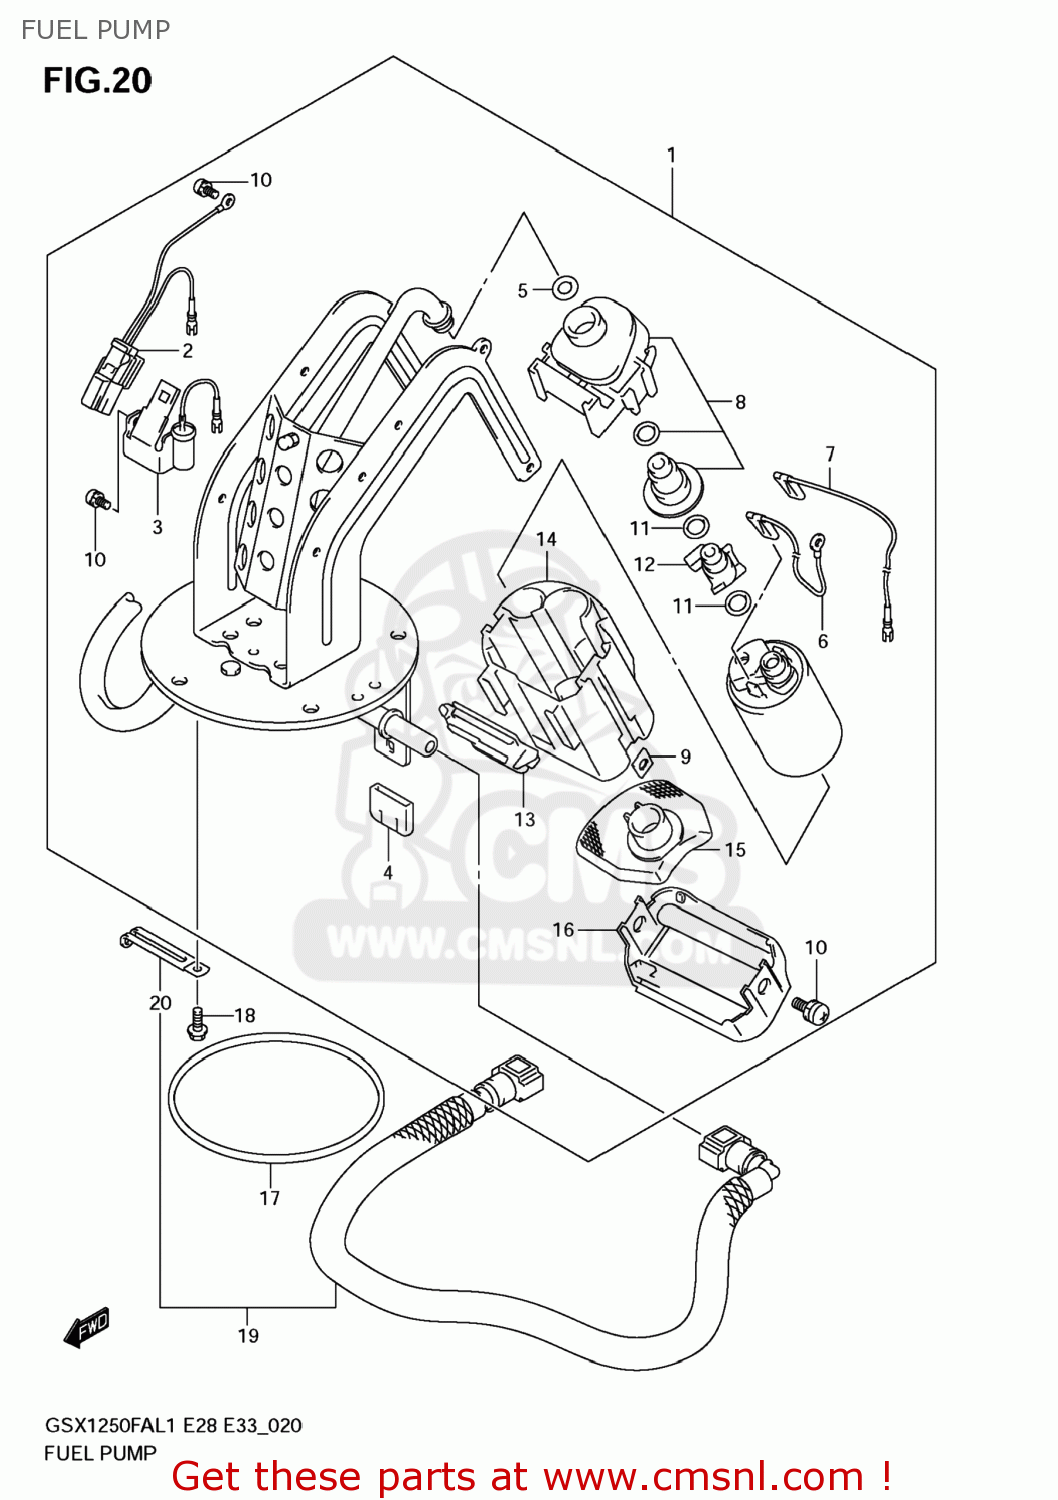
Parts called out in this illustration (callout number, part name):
1	PUMP ASSY,FUEL
2	HARNESS,GAUGE
3	THERMISTOR
4	CAP,STAY
5	O RING
6	WIRE,EARTH
7	WIRE,LEAD
8	REGULATOR
9	STOPPER
10	SCREW
11	O RING
12	JOINT
13	COVER,CUP
14	CUP
15	STRAINER
16	COVER,DUST
17	O RING,FUEL PUMP
18	BOLT
19	HOSE COMP,FUEL
20	CLAMP(L:45)
